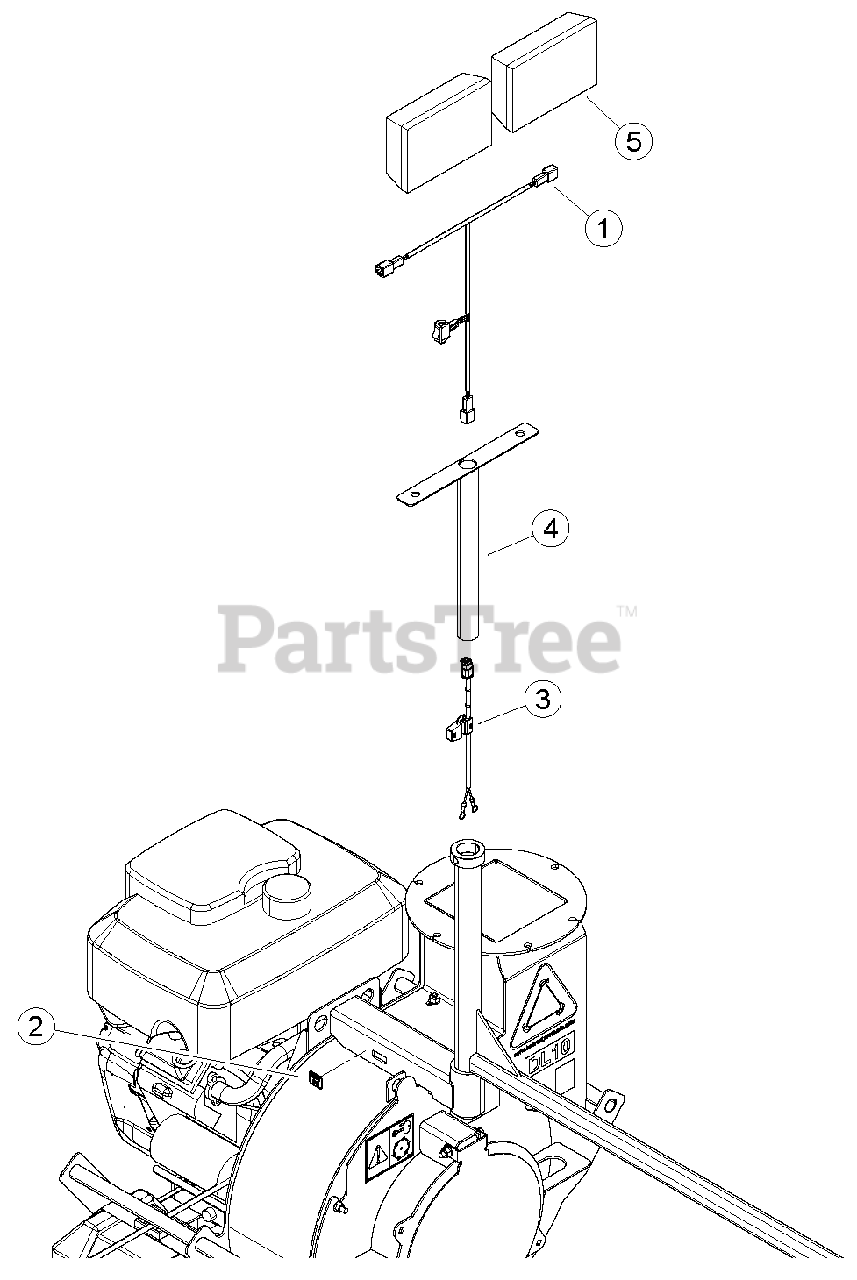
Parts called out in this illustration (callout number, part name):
1	HARNESS, DEUTSCH TO DEUTSCH
2	DECAL, LIGHTS
3	HARNESS, DEUTSCH TO RING
4	WELDMENT, MOUNT LIGHTS
5	LAMP, 4 X 6 HALOGEN W DEUTSCH
